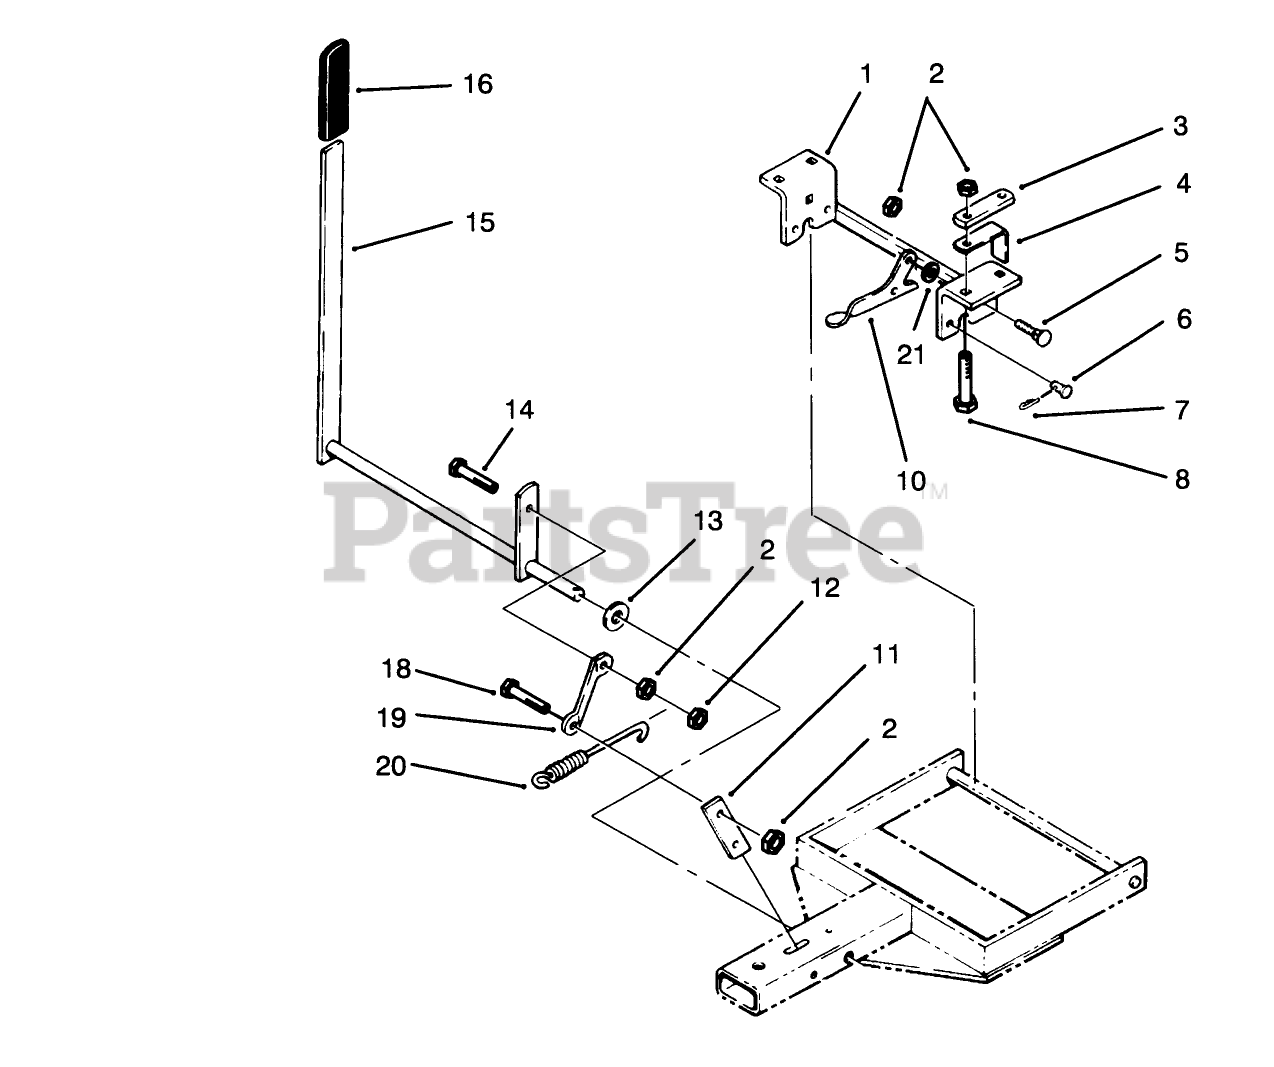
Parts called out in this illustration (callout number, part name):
1	Bracket
2	NUT-LOCK, NI
3	BRACKET-REAR LINK MOUNTING
4	SPACER-BRACKET
5	BOLT-CARR
6	PIN-CLEVIS
7	Hairpin
8	SCREW-CARR
10	PLATE-LATCHING
11	Latch
12	NUT-HEX, JAM
13	WASHER-FLAT
14	SCREW-HH
15	ASS'Y-LATCH HANDL R
16	GRIP
18	SCREW-HH
19	Latch Link
20	SPRING
21	WASHER-FLAT
